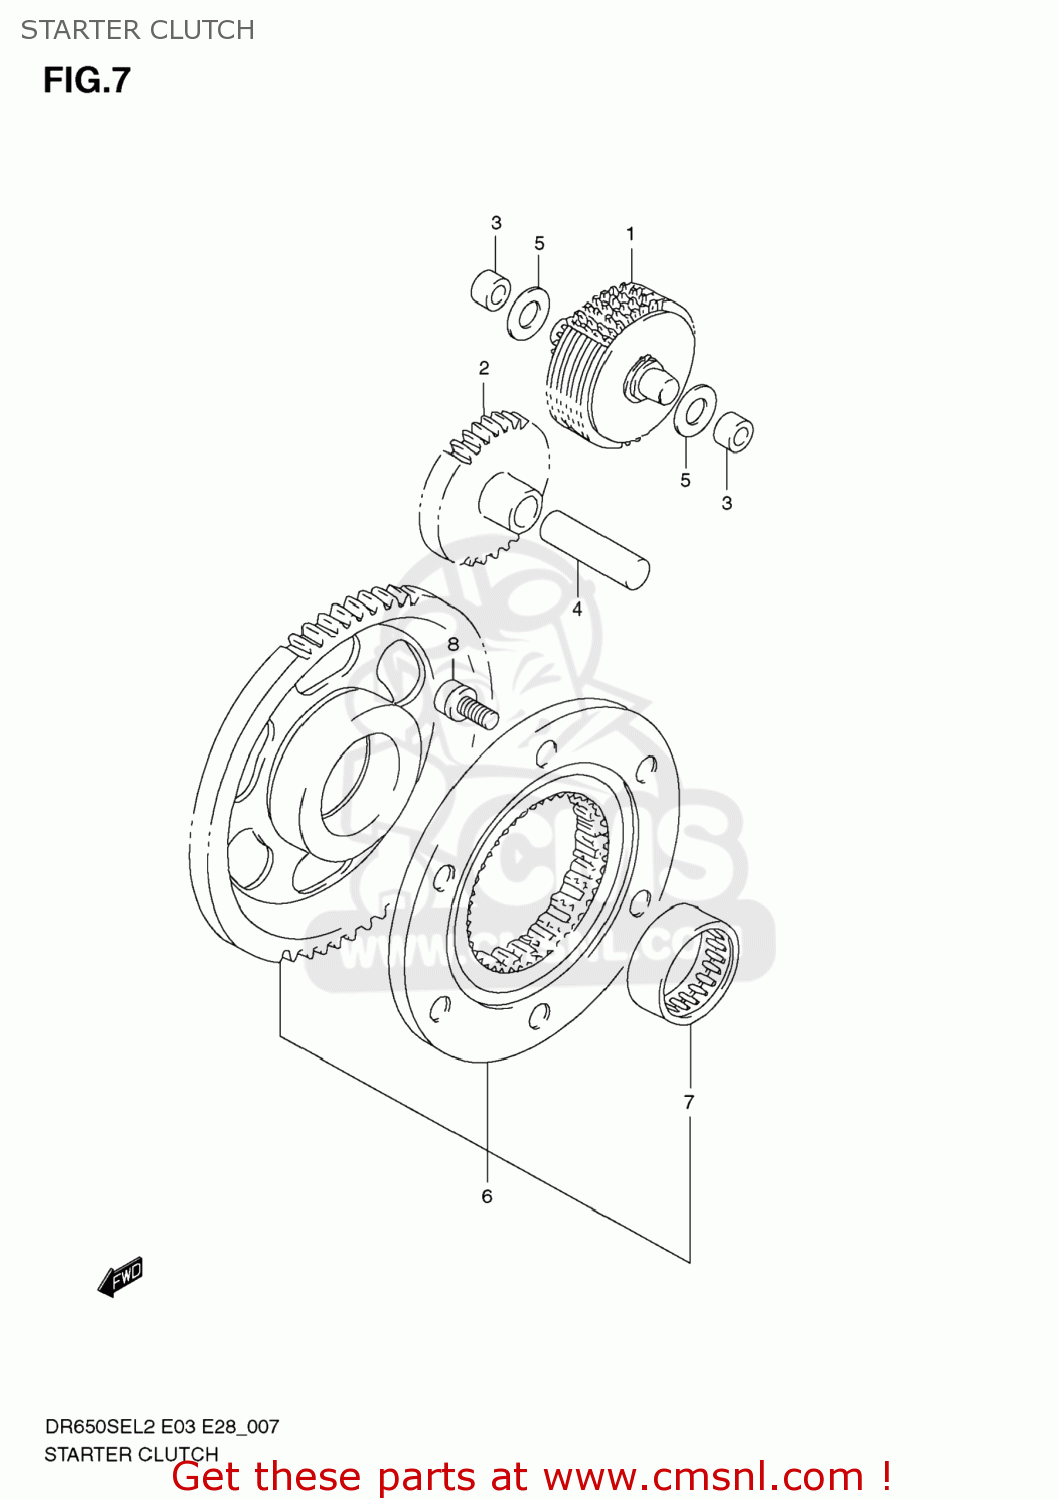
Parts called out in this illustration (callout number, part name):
1	LIMITER ASSY,STARTER IDLE GEAR
2	GEAR,STARTER IDLE NO.2(NT:27)
3	BUSH,LIMITER GEAR SHAFT
4	PIN
5	WASHER
6	CLUTCH SET,STARTER
7	BEARING(31X39X17.8)
8	BOLT(8X20)
